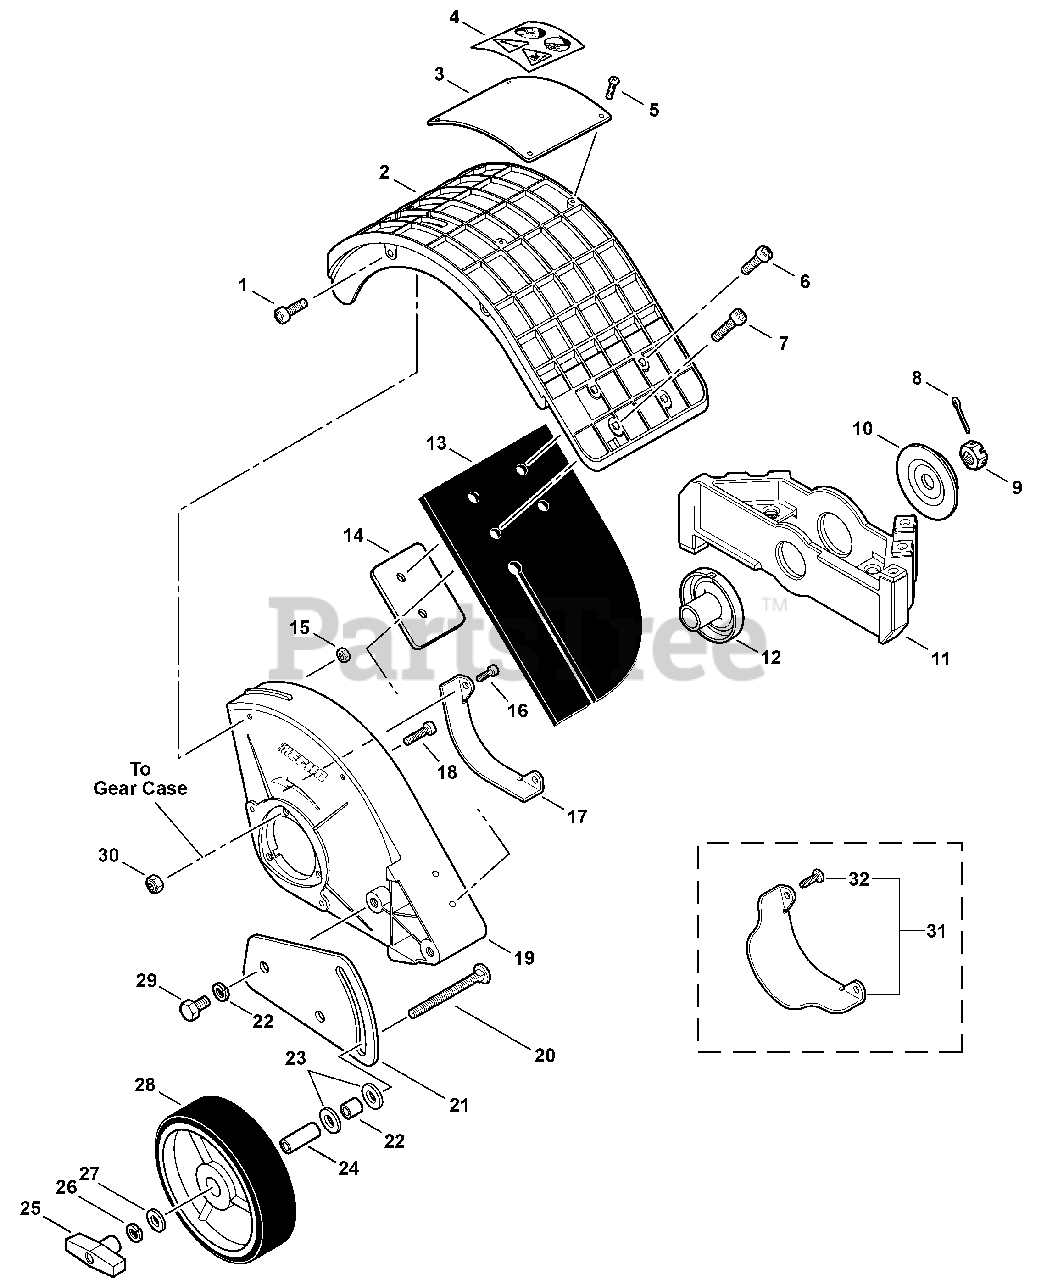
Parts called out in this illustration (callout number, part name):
1	SCREW - 4×12
2	COVER, SHIELD
4	LABEL - CAUTION
6	SCREW - 4×12
7	SCREW - 4×16 -- TAPPING
8	PIN, SPLIT - 2×22
9	LOCKNUT - LEFT HAND
10	ADAPTER, BLADE - LOWER
11	BLADE, REDEFINING
12	ADAPTER, BLADE - UPPER
13	FLAP, DEBRIS
14	PLATE, FLAP
15	LOCKNUT - 4
16	SCREW - 4×12
18	SCREW - 5×20
19	SHIELD, BLADE
21	BRACKET,WHEEL
23	WASHER - 10
24	COLLAR - 12
25	WINGNUT - 5/16-18
26	LOCKWASHER - 8
27	WASHER - 8
28	WHEEL - 6×1.5
29	BOLT - 8×14
30	LOCKNUT - 5
31	SHIELD GUARD KIT
32	SCREW - 4×12 -- TAPPING
